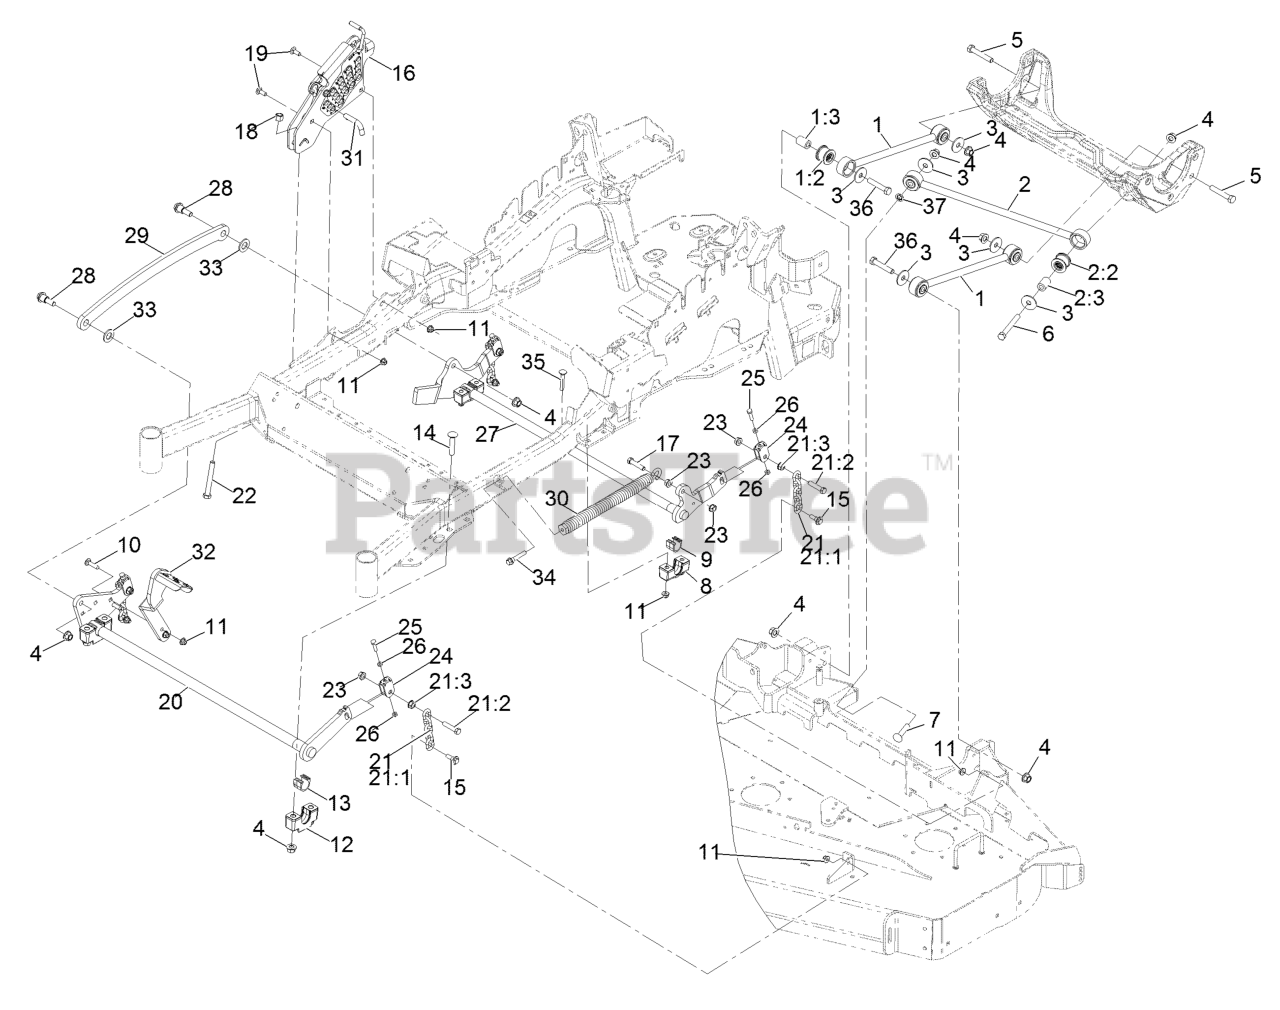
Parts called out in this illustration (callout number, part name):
1	DECK STRUT ASM
1:2	BUSHING-SUSPENSION, RUBBER
2	PANHARD ROD ASM
2:2	BUSHING-SUSPENSION, RUBBER
3	WASHER-THRUST
4	Nut-Lock 1/2-13
5	SCREW-HH
6	SCREW-HH
7	SCREW-CARR
8	SUPPORT-CROSS SHAFT, BEARING REAR
9	BEARING-CROSS SHAFT, REAR
10	SCREW-CARR
11	NUT-HF, NI
12	SUPPORT-CROSS SHAFT, BEARING
13	BEARING-CROSS SHAFT, FRON
14	Bolt-Carriage 1/2-13 X 2 1/2 Spl Neck
15	SCREW-SHOULDER, HHF
16	HOC ASM
17	SCREW-HH
18	NUT-LOCK, NI
19	BOLT-CARR
20	DECKLIFT-FRONT
21	DECK LIFT CHAIN ASM
21:1	CHAIN-LIFT, DECK
21:2	SCREW-HH
22	BOLT-TAP
24	YOKE-ADJUST, DECK
25	SCREW-HH
26	NUT-JAM
27	LIFT-DECK, REAR
28	SCREW-SHOULDER, HHF 1/2-13 X 1.12
29	LINK-LIFT, DECK
30	SPRING-EXTENSION
31	PIN-HOC
32	LEVER-FOOT
33	WASHER-FLAT
34	BOLT-SHOULDER
35	Bolt-Carriage 3/8-16 X 2 1/4
36	SCREW-HH
37	NUT-PUSH
